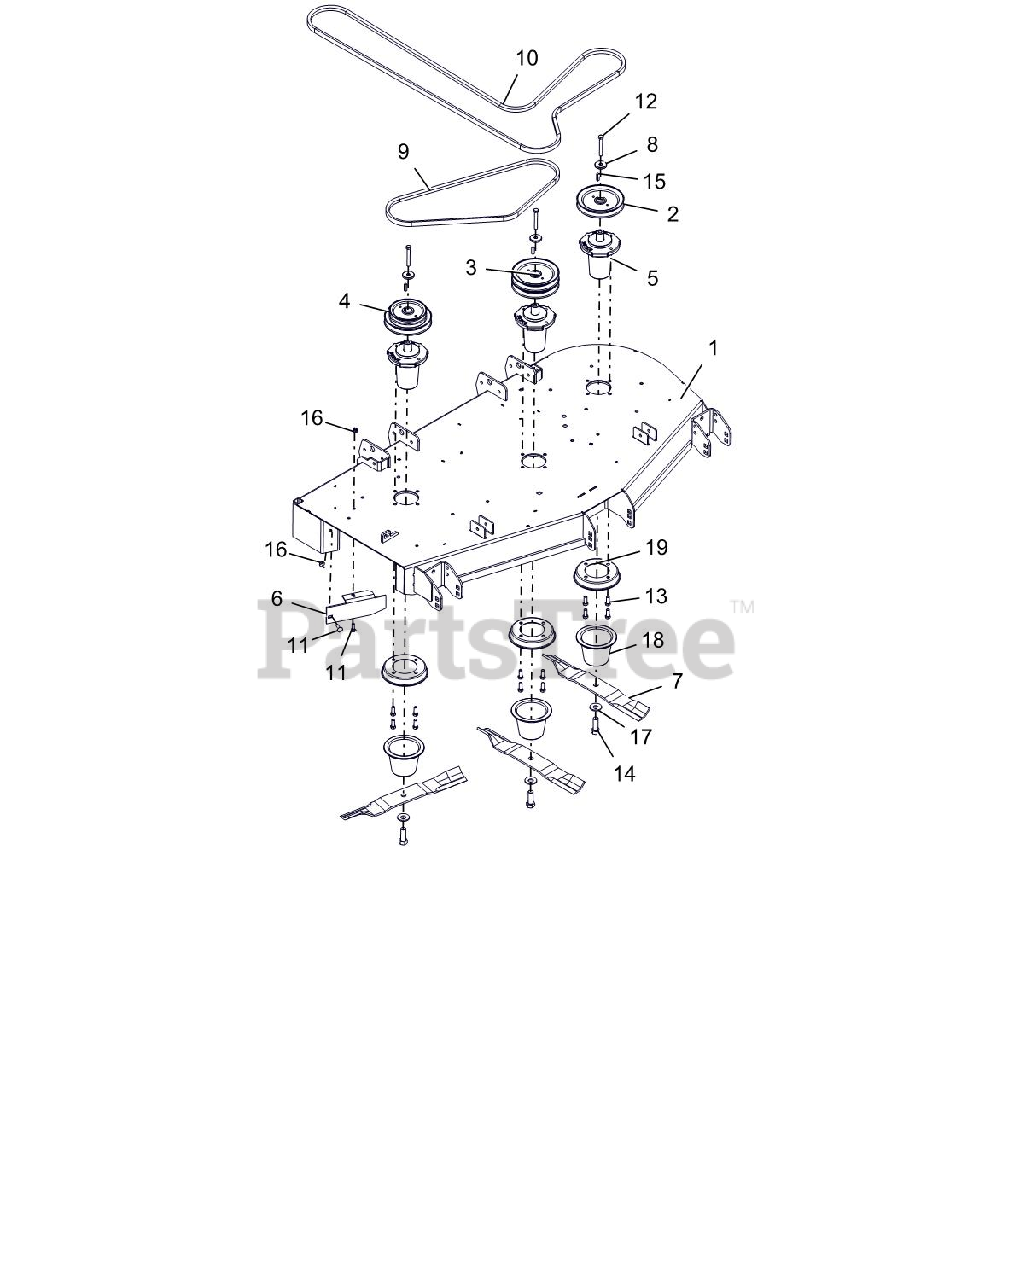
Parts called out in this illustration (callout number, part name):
1	DECK, PT52 W/SAFETY DECALS
2	PULLEY, SINGLE-1"ID X 6" OD
3	PULLEY, DOUBLE
4	PULLEY, DBL-1"IDX6.00"&4.75"OD
5	ASM, MAINT FREE SPINDLE
6	52" DISCHARGE BAFFLE - RED
7	BLADE, 18.00" MOWER (HI-LIFT)
8	RETAINER, SHEAVE
9	V-BELT, B-COGGED
10	BELT, B-SECTI0N EPDM RAW EDGE
11	@BLT-RDHDSQNK .31-18X1.00 G5YZ
12	BLT-HEX .38-16X2.75 GR8 YWZC
13	BLT-HEX .38-16X1.0 GR8 YZ EP30
14	BLT-HEX .62-18X1.75 GR8 YWZC
15	KEY, SQ .25X.25X1.00 RC 40-50
16	@NUT-LK-NYL-FLG .31-18 YWZC
17	WSHR-BLVL .669X1.535X.138
18	GUARD, SPINDLE LOWER
19	GUARD, SPINDLE TOP
